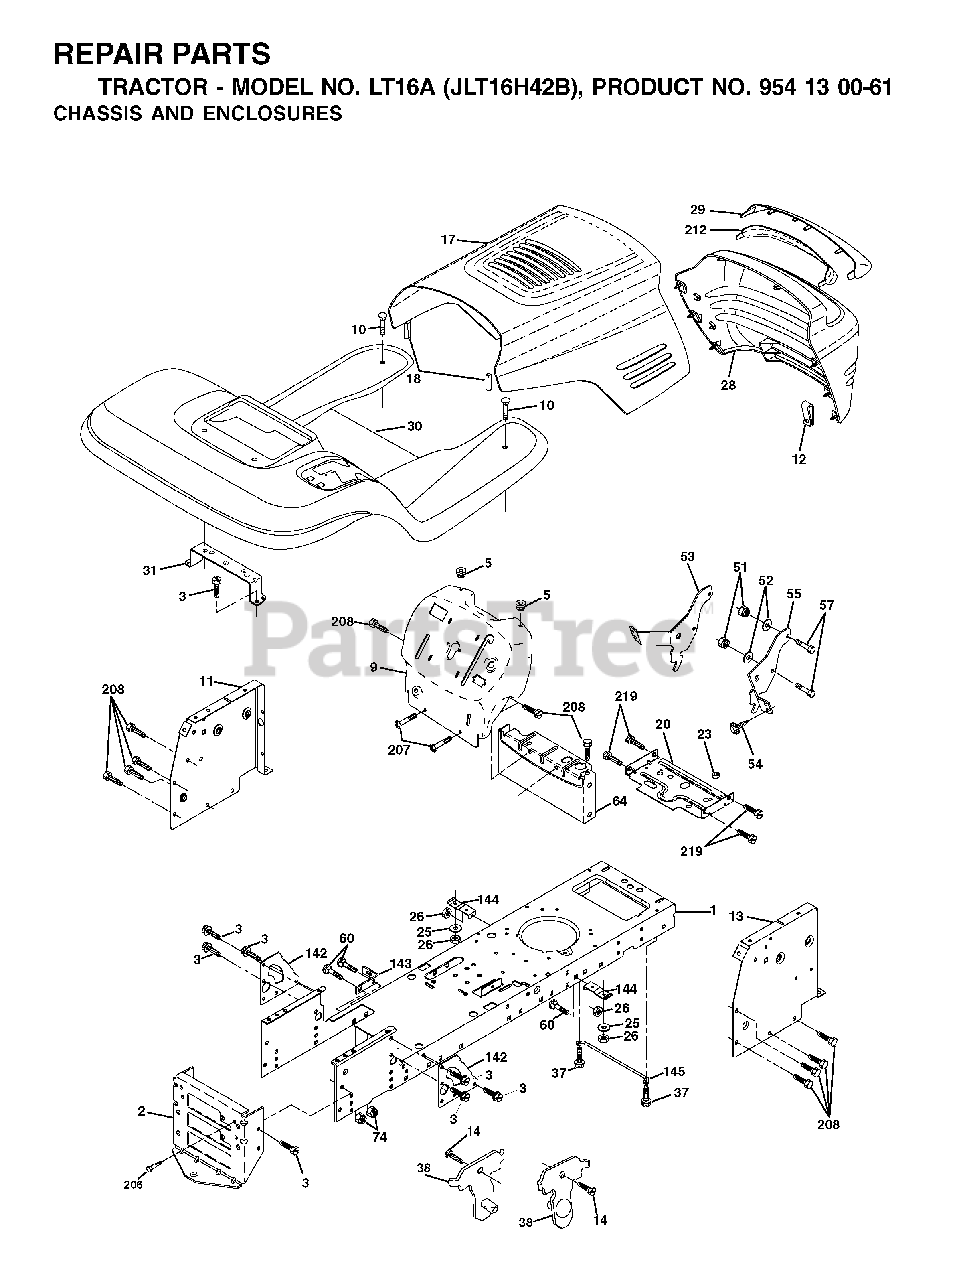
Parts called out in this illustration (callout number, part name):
1	CHASSIS STAMPING
2	DRAWBAR, 12GA
3	SCREW 3/8-16X3/4
5	BUMPER.RUBBER.HOOD
10	BOLT D
11	PANEL.DASH.LH.LTX
13	PANEL ASM, DASH RH
18	BUMPER HOOD T
20	PLATE MTG.BATTERY/FUEL TANK
23	GROMMET T
25	WASHER
26	NUT
38	BRACKET.ASM.PIVOT.MOWER.REAR
51	LOCKNUT
57	BOLT
64	DASH LOWER
74	LOCKNUT
142	PLATE REINFORCEMENT
143	BRACKET, SWAY BAR
144	BRKT, FOOT REST
145	ROD PIVOT CHASSIS/HOOD
206	SHOULDER BOLT 5/16-18TT
207	SCREW, 5/16-18 X 1/2
208	SCREW 3/8-16X1/2
219	SCREW
